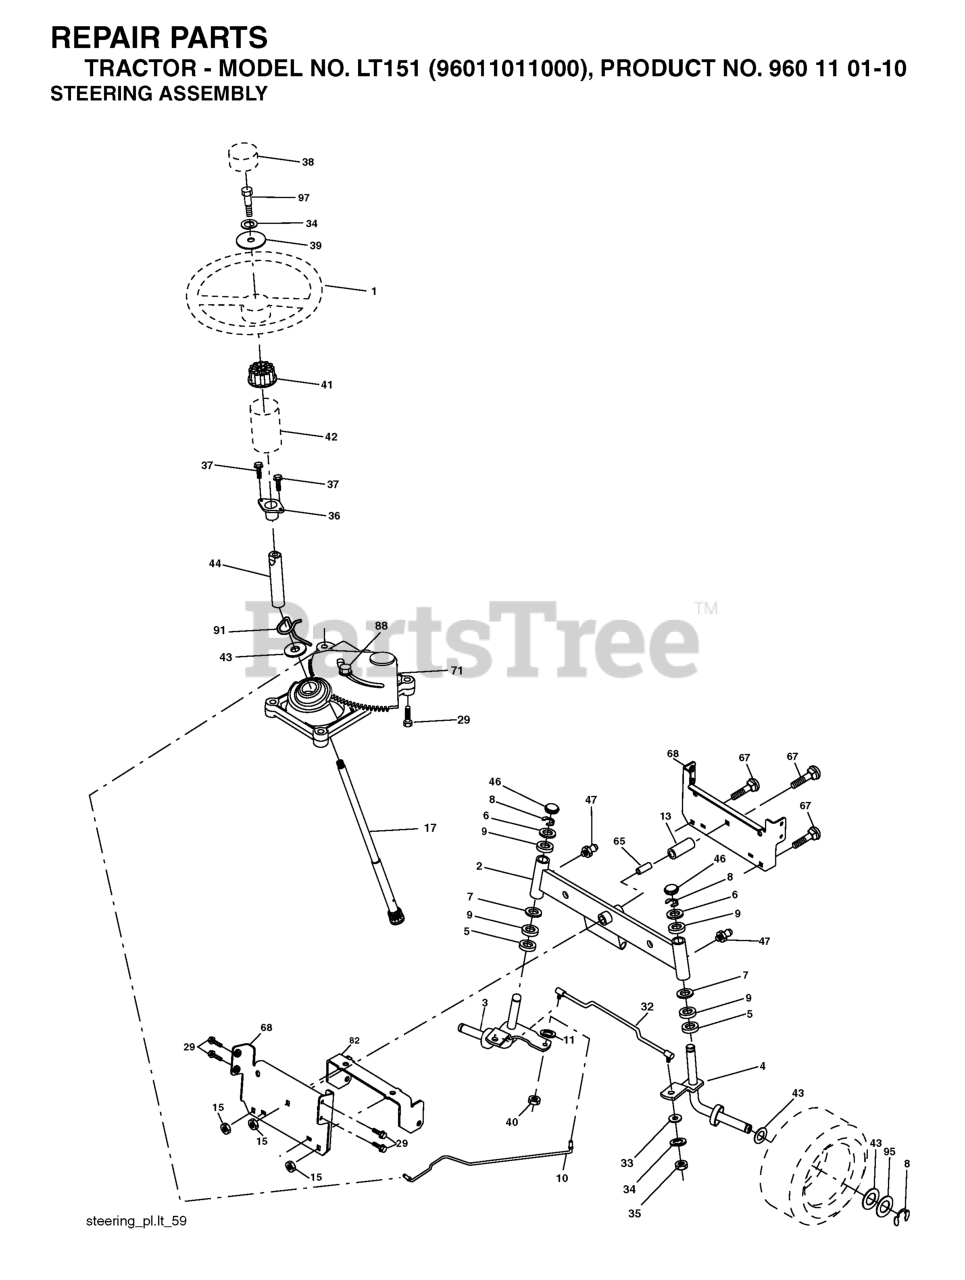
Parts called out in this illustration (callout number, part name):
1	WHEEL.STEERING.LEGEND2.GRY
2	AXLE ASM.
3	SPINDLE.ASM.LH.15"TIRES
4	SPINDLE.ASM.RH.15"TIRES
5	THRUST WASHER
9	BRNG T
10	DRAGLINK.15".TIRES.2001
11	WASHER, LOCK 3/8
13	TUBE, PIVOT AXLE
15	NUT
17	SHAFT STEERING SPLINE
29	SCREW, 3/8-16X3/4
33	WASHER M
34	WASHER.LOCK.HVY.HLCL.SPR.5/16
35	NUT, CROWNLOCK
36	BUSHING, STEERING
37	SCREW.TT.#10-32X.5.3/8.FLANGE
38	INSERT.CAP.STRG.WH.GRAY
39	WASHER.11/32
40	NUT CROWNLOCK 3/8-24
41	ADAPTER, WHEEL STNG..
42	BOOT STEERING
44	SHAFT.EXTEN.STRG.SPLINE
46	CAP.SPINDLE.BLACK
47	FITTING.GREASE.TAPERED
65	SPACER BRACE AXLE
67	BOLT CARRIAGE
68	BRACE.AXLE.15"TIRES
71	STEERING ASM
82	BRACKET.SUSP.CHASSIS.FRONT.15
88	BOLT, SHOULDER 7/16-20
91	CLIP.STEERING
95	WASHER.HARDENED
